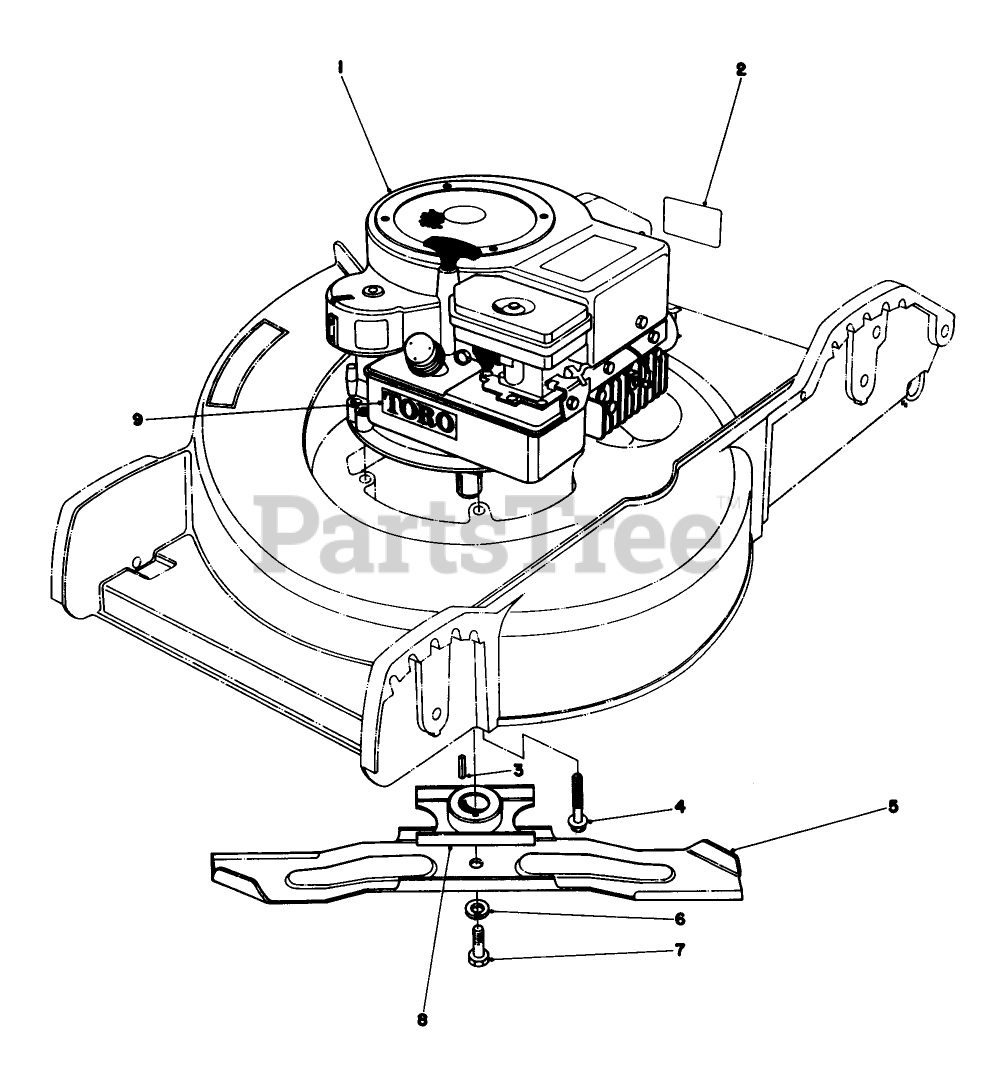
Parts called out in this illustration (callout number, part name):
1	Engine
3	KEY-SQUARE
4	3/8-16 X 2 CAPSCREW
5	Blade
6	WASHER-LOCK
7	SPECIAL SCREW
8	Blade Retailer
9	Decal Toro
